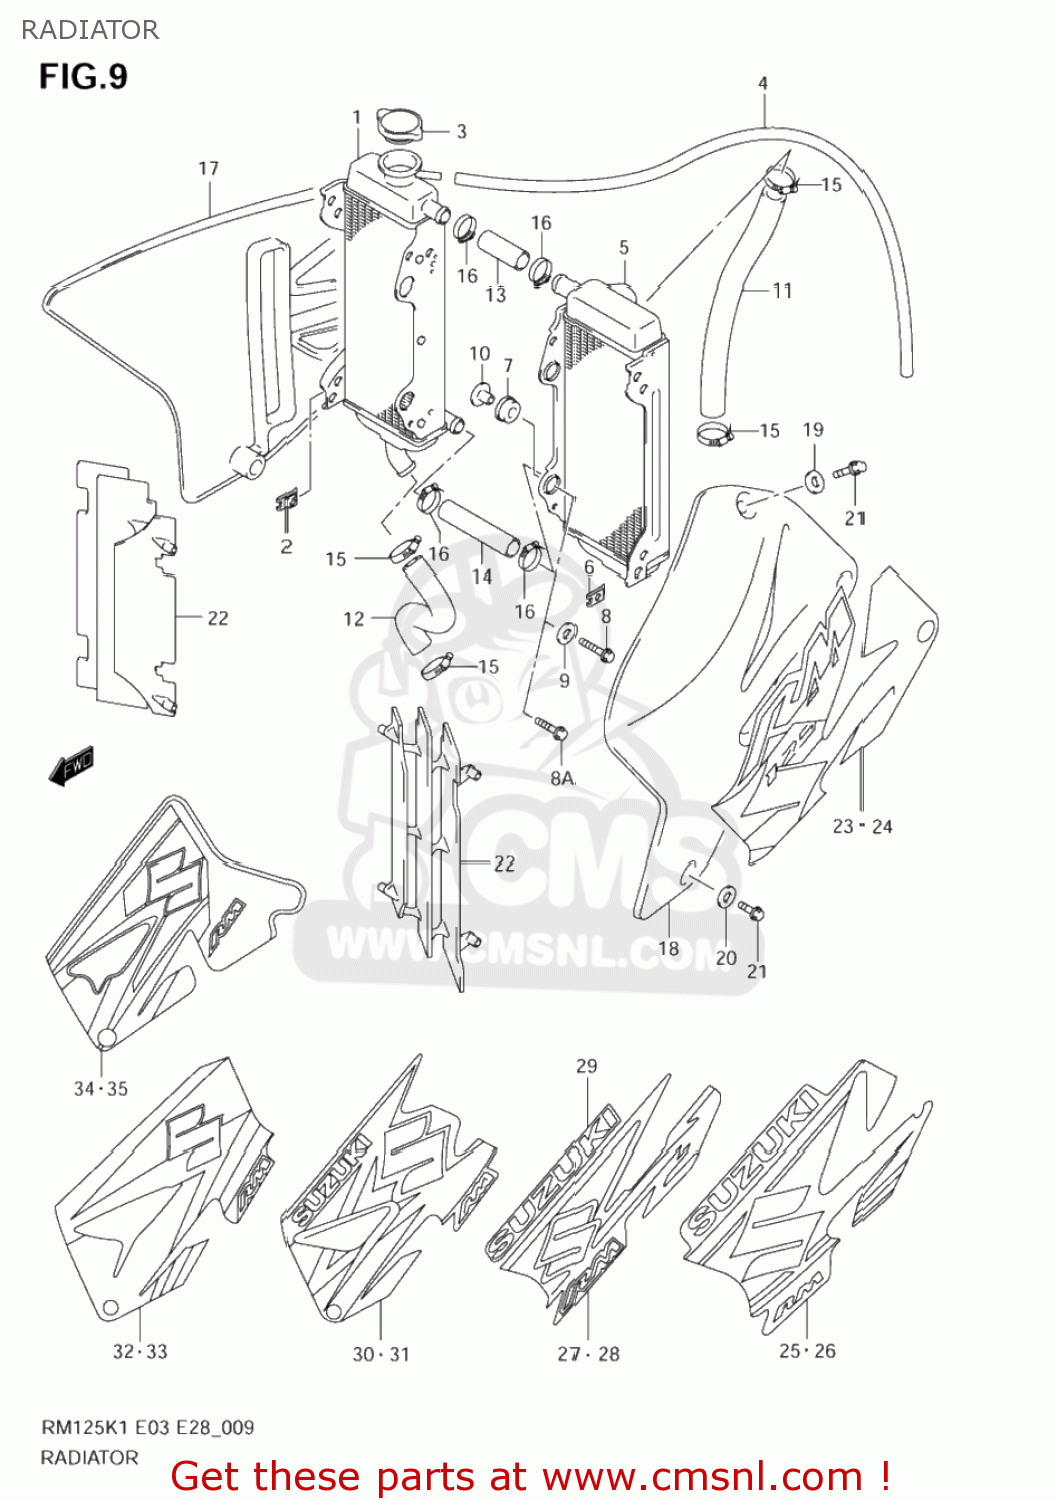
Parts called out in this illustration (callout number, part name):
1	RADIATOR,WATER,R
2	NUT
3	CAP COMP,RADIATOR
4	HOSE(5X8X1000)
5	RADIATOR,WATER,L
6	NUT
7	CUSHION,RADIATOR LWR
8	SCREW
8A	BOLT(6X25)
9	WASHER(6.5X24X1.2)
10	SPACER(6.5X10.5X14.1)
11	HOSE,RADIATOR INLET
12	HOSE,RADIATOR OUTLET
13	HOSE,RADIATOR
14	HOSE,RADIATOR JOINT
15	CLAMP
16	CLAMP
17	COVER,RDTR,R
18	COVER,RDTR,L
19	WASHER
20	WASHER
21	BOLT
22	LOUVER,RADIATOR
23	TAPE, RADIATOR COVER RH
24	TAPE, RADIATOR COVER LH
25	TAPE,RADIATOR COVER,R
26	TAPE,RADIATOR COVER,L
27	TAPE, RADIATOR COVER RH
28	TAPE,RADIATOR COVER,L
29	EMBLEM,SUZUKI
30	TAPE,RADIATOR COVER,R
31	TAPE,RADIATOR COVER,L
32	TAPE,RADIATOR COVER,R
33	TAPE, RADIATOR COVER LH
34	TAPE, RADIATOR COVER RH
35	TAPE, RADIATOR COVER LH
